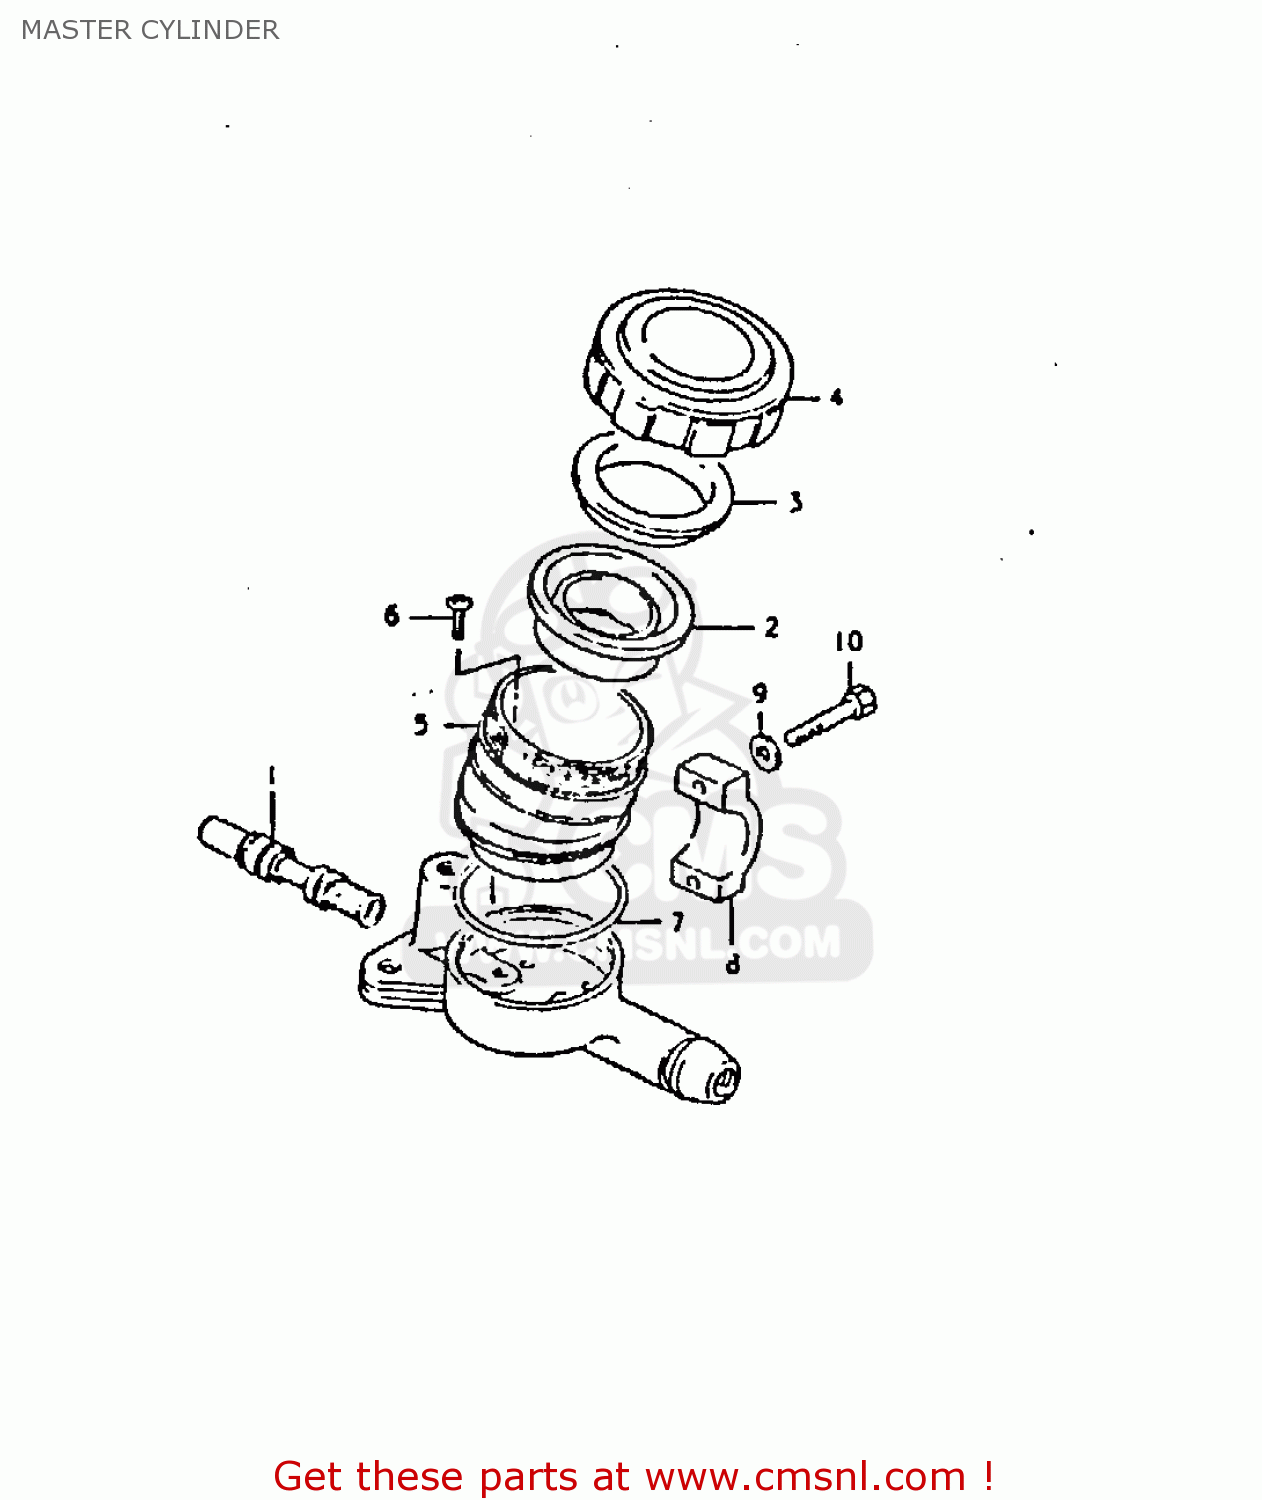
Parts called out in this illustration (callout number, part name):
1	PISTON & CUP SET
2	DIAPHRAGM
3	PLATE,DIAPHRAGM
4	CAP
5	RESERVOIR
6	SCREW,MASTER CYLINDER
7	O RING
8	HOLDER,MASTER CYLINDER
9	WASHER
10	BOLT
